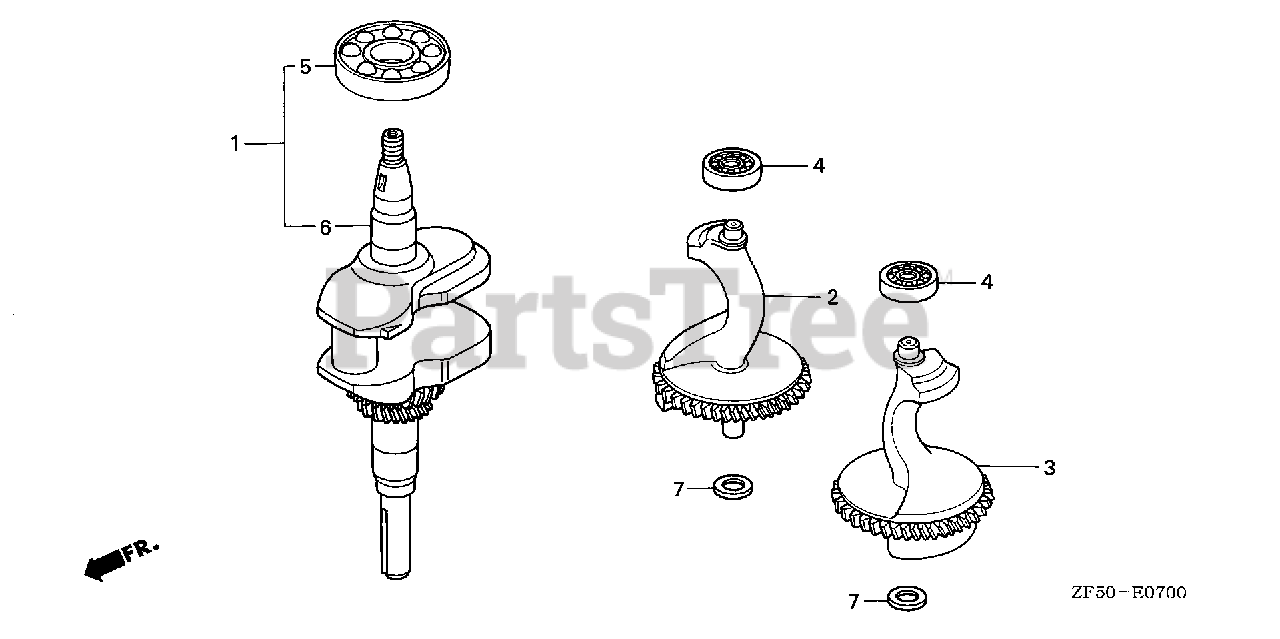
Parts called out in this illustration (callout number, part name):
1	CRANKSHAFT
1	CRANKSHAFT (NOT AVAILABLE)
2	WEIGHT A, BALANCER
3	WEIGHT B, BALANCER
4	BEARING, RADIAL BALL (6202)
5	BEARING, RADIAL BALL (6207)
6	CRANKSHAFT
7	WASHER, THRUST (15MM)
